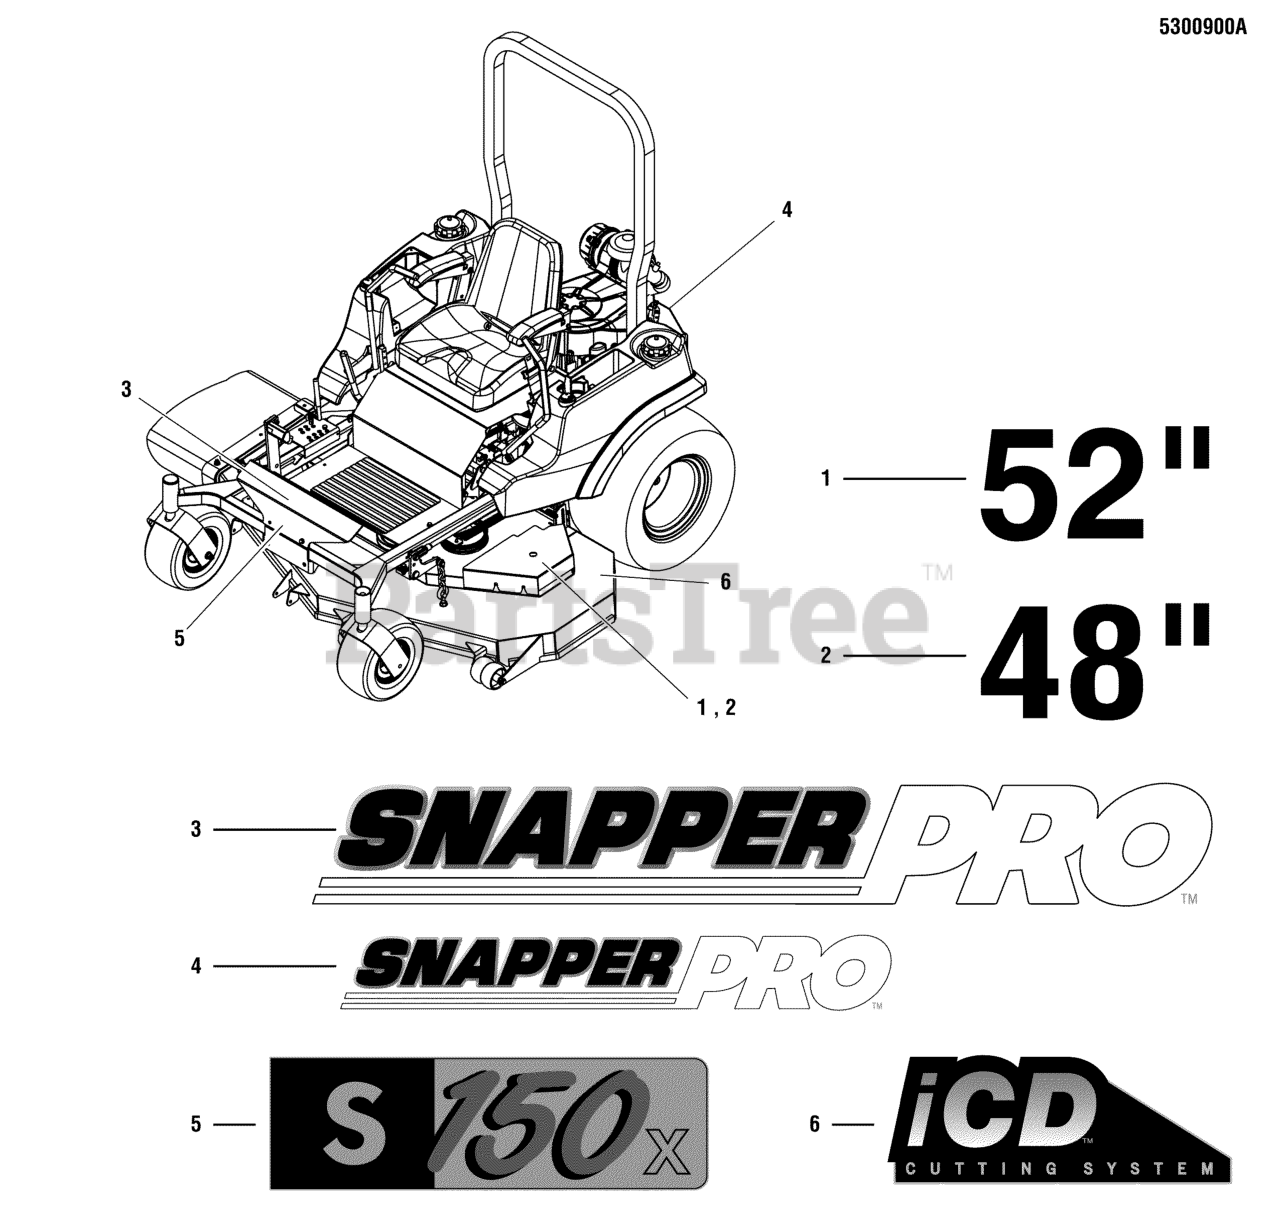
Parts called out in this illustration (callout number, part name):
1	DECAL, 52
2	DECAL, 48
3	DECAL, S150X, FRONT
4	DECAL, SNAPPER PRO, HEAT
5	DECAL, S150X
5	DECAL, S150XT
6	DECAL, iCD CUTTING SYSTEM
